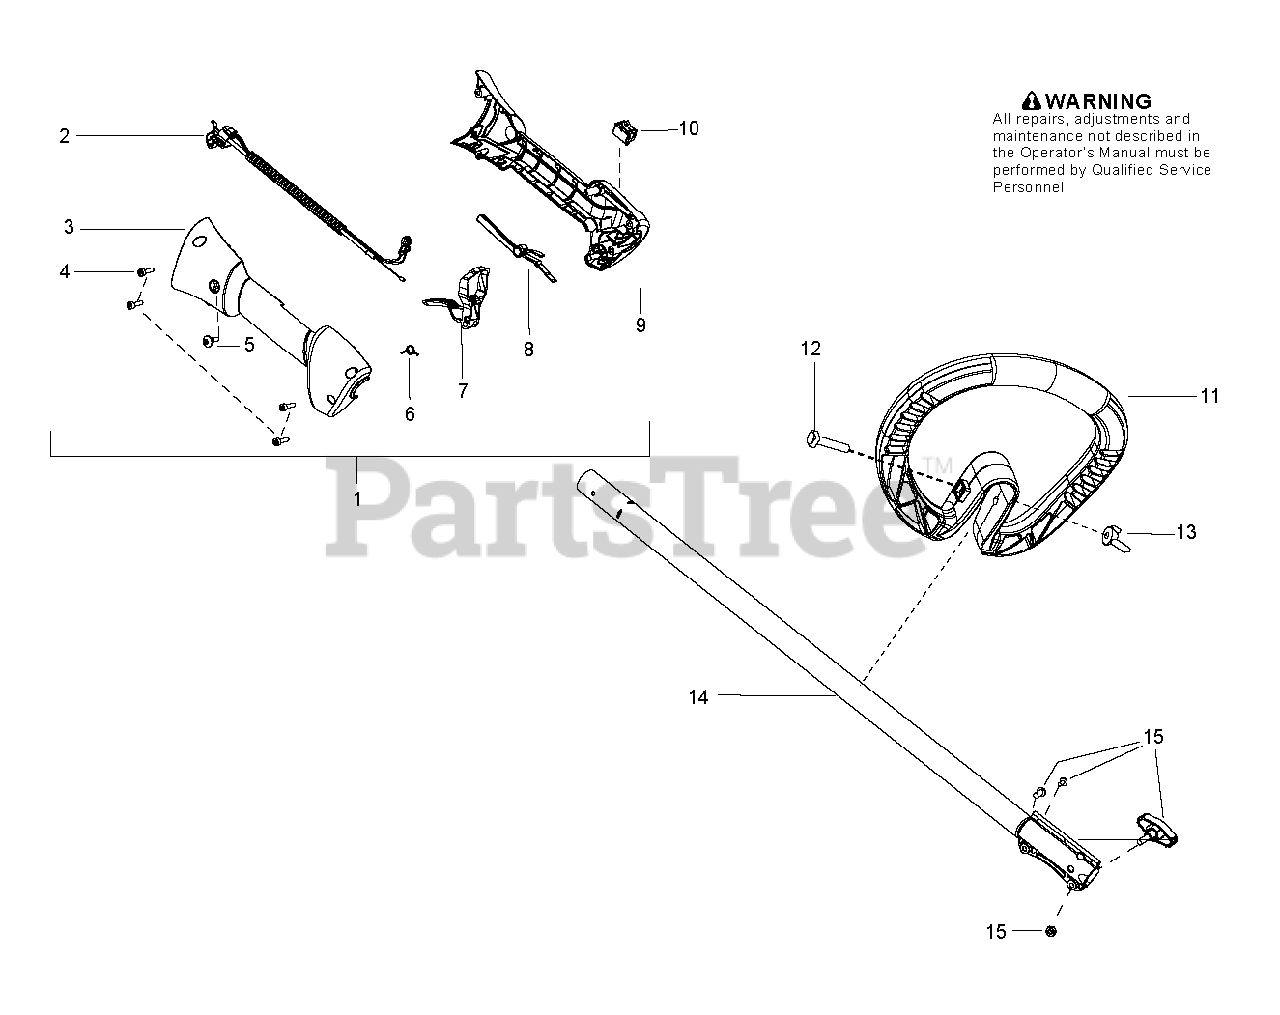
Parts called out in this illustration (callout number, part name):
2	ASSY CABLE/WIRE HARNESS
3	HANDLE HALF RIGHT
4	SCREW M4 X 1.75 PT 16MM
5	SCREW M4 X 1.75 PT 16MM
8	LOCKOUT TRIGGER
9	HANDLE HALF LEFT
10	STOP SWITCH
11	HANDLE ASSIST 1"
12	BOLT, TYPE 2
13	WINGNUT, TYPE 2
14	Drive Shaft Kit, Upper
15	ASSY COUPLER BLACK
